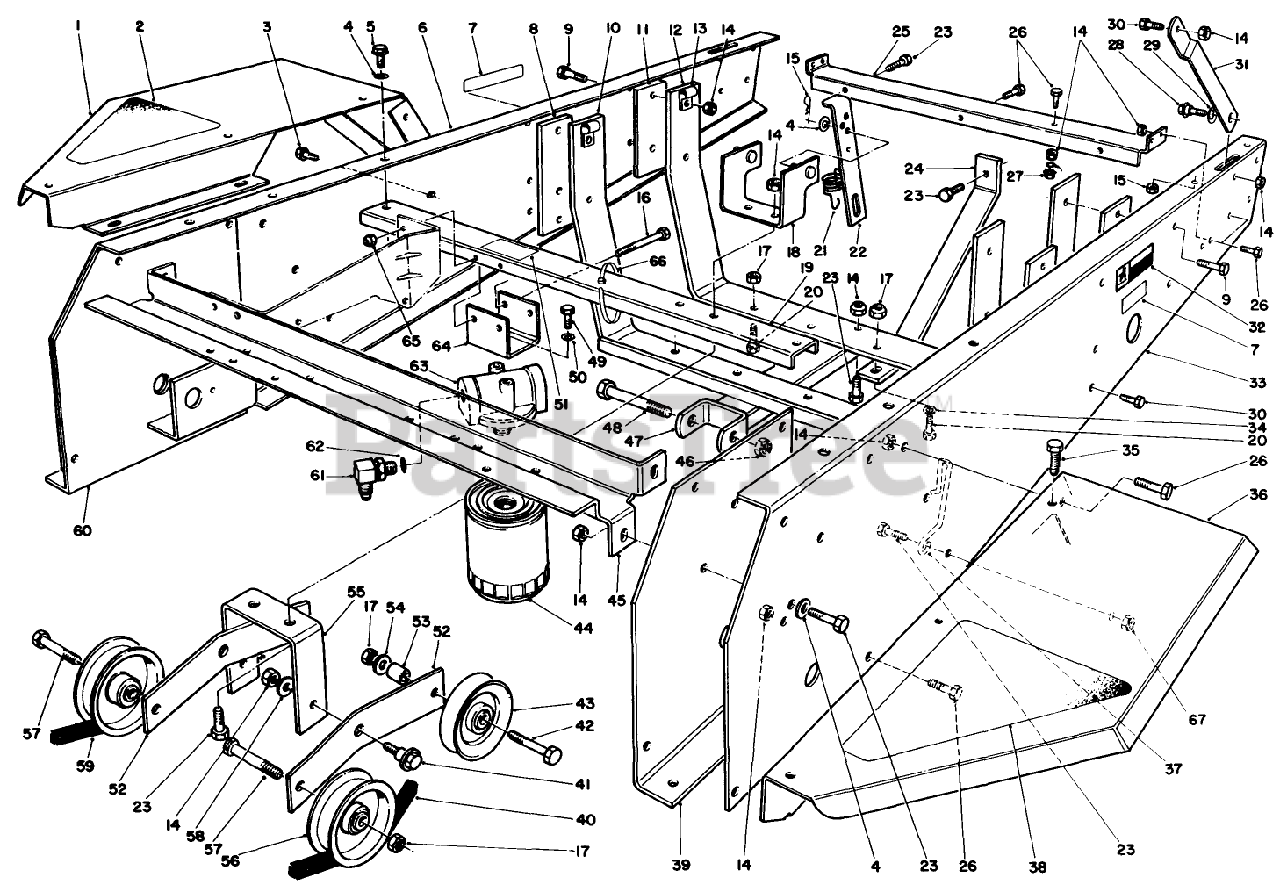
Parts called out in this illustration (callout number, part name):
1	Fender R.H
2	RH FENDER PAD
3	SCREW-HHF
4	WASHER-PLAIN
5	SCREW-HWHTF
6	Channel-Side R.H.
7	DECAL-WARNING
8	FRONT ENG PLATE
9	SCREW-HH
10	ENGINE MT WA B
11	REAR ENG PLATE
12	ENGINE MOUNT B
14	NUT-LOCK, NI
15	PIN-COTTER
16	SCREW-HH
17	NUT-LOCK, NI
18	Anchor-Spring
19	MIDDLE CHANNEL WA B
20	SCREW-HH
21	IDLER SPRING
22	IDLER ANCHOR LINK
23	SCREW-HH
24	TENSION BAR B
25	Support-Shield
26	SCREW-HH
27	NUT-KEPS
28	SCREW-SHOULDER
29	WASHER-SPRING
30	SCREW-HH
31	Stop-Hood Lower
32	DECAL-HOT
33	Channel-Side LH.
34	WASHER-LOCK
35	SCREW-HHFTF
36	Fender L.H.
37	BELT GUIDE
38	LH FENDER PAD
39	Axle Stand-LH.
40	V-BELT, JACKSHAFT
41	SCREW-SHOULDER
42	SCREW-HH
43	PULLEY
44	FILTER-OIL, TRANSMISSION
45	Channel-Front
46	NUT-LOCK
47	CYL MOUNT WA B
48	SCREW-HH
49	SCREW-HH
50	WASHER-LOCK
51	DECAL-OIL
52	IDLER LEVER
53	SPACER-WEIGHT
54	WASHER-FLAT
55	IDLER MT BRKT
56	PULLEY
57	SCREW-HH
58	WASHER
59	V-BELT, TRACTION
60	Axle Stand R.H.
61	FITTING-ELBOW, 90
62	O-RING
63	FILTER HD ASM
64	BRACKET - FILTER HEAD
65	NUT-LOCK, NI
66	TIE-CABLE
67	NUT-HF
